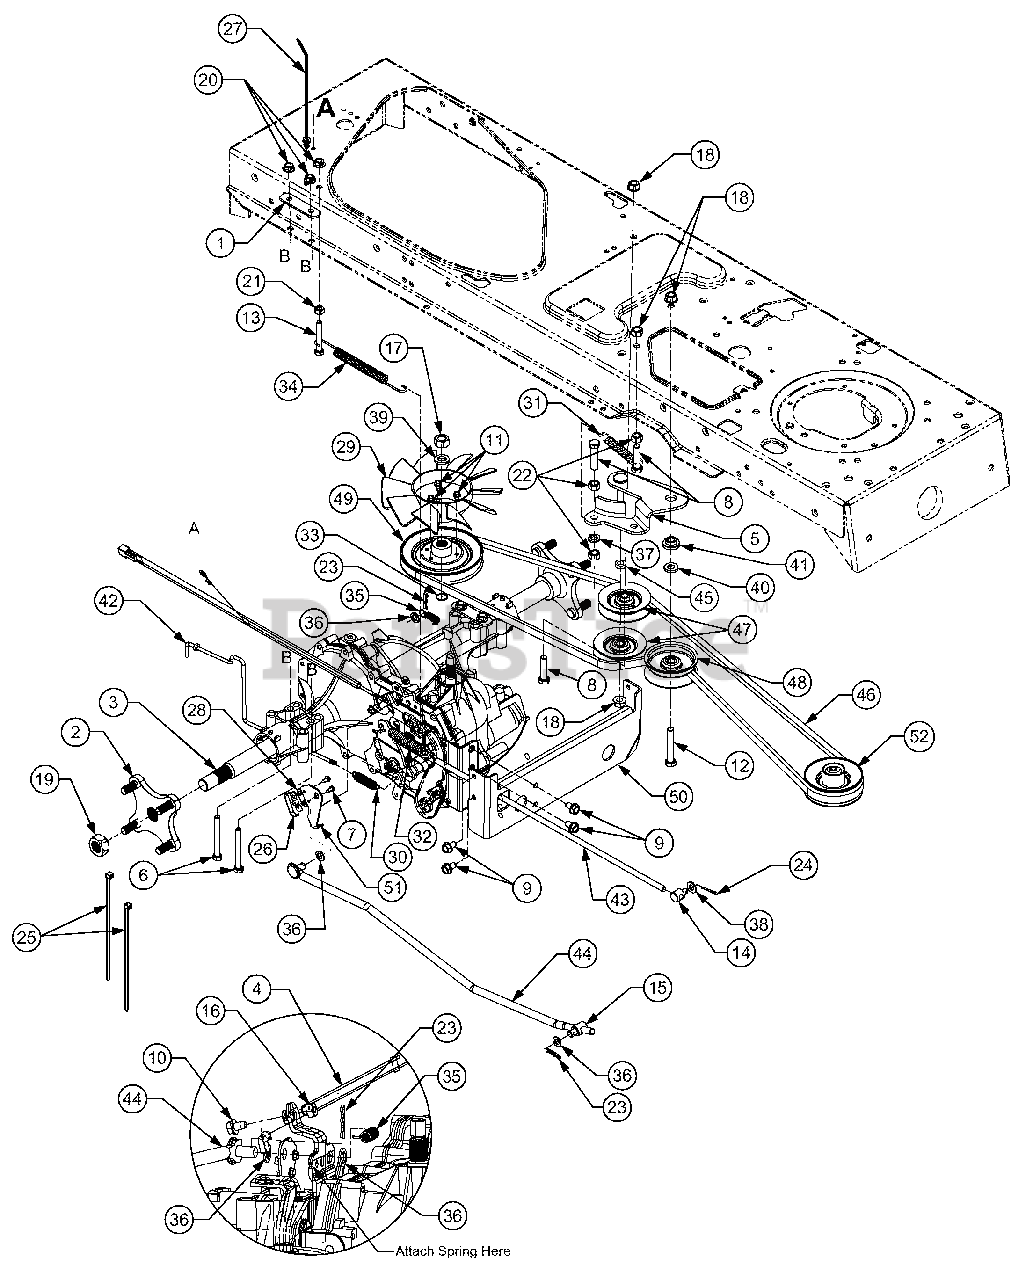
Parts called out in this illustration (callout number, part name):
2	Hub Assembly, Wheel
3	Transmission, Hydrostatic
4	Harness Assembly, Ground & Reverse
5	Bracket Assembly, Idler, Center Dbl
6	Hex Cap Screw, 5/16-18, 2.75, Gr5
7	Screw, #8-18, 0.500
8	Hex Cap Screw, 3/8-16, 1.50, Gr5
9	Screw, 5/16-12, 0.75
10	Screw, 1/4-20, 0.5
11	Screw, #12-24, 0.375
12	Hex Cap Screw, 3/8-16, 2.25, Gr5
13	Hex Cap Screw, 5/16-18, 2.00, Gr5
14	Ferrule, 5/16-18 x .312 Dia
15	Ferrule, 3/8-24 x .375 Dia
16	Nut, Hex Lock, 1/4-20
17	Nut, Hex, 1/2-20, Gr2
18	Nut, Flange Lock, 3/8-16
19	Nut, 3/4-16, Grb, Hx
20	Nut, Flange Lock, 5/16-18, Gr5
21	Nut, Hex, 5/16-18, Gr5
22	Nut, Hex, 3/8-16, Gr8
23	Pin, Cotter, .072 Dia. x 1.13 Lg
24	Pin, Cotter, 3/32, 1.0
25	Cable, Tie, 3/16 x .05 x 7.4
26	Switch, Spring, Short
27	Tie, Cable, Push Mount 7.5 Lg
28	Plate, Insulator Nut
29	Fan, Blade, 10"
30	Spring, .48 OD x 2.03 Extension
31	Spring, Extension, .50 Dia x 3.97 Lg
32	Spring, Extension, .59 OD x 4.00 Lg
33	Ring, Wire
34	Spring, Extension, .500 Dia x 7.0 Lg
35	Spring, Extension, 3/8 OD x 1.44 Lg
36	Washer, Flat, .385 x .62 x .063
37	Washer, Lock, 3/8, Regular Duty
38	Washer, Flat, .344 x .688 x .065
39	Washer, Lock, 1/2, Regular Duty
40	Washer, Flat, .407 x .812 x .135 Hdn
41	Spacer, Shoulder, 1.00 x .38 x .38
42	Rod, Hydro Bypass
43	Rod, Brake, Hydro
44	Rod, Control, Hydro
45	Spacer, .376 ID x .625 OD x .22
46	Belt, V Type, Poly
47	Pulley, Idler, V Type x 3.06 Dia
48	Pulley, Idler, Flat 2.75 OD
49	Pulley, Input, 5.0 Dia
52	Pulley, Engine, 3.56 Dia.
